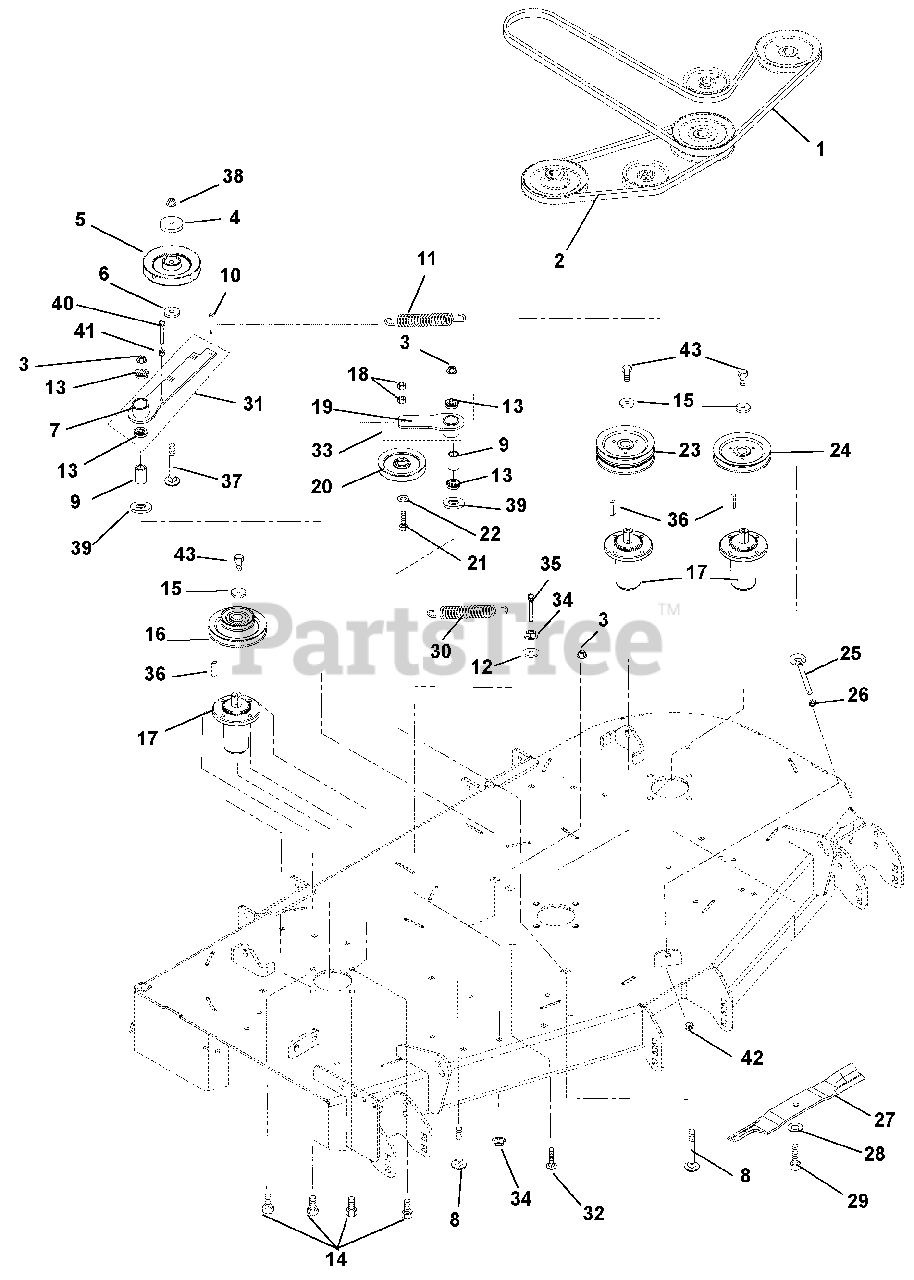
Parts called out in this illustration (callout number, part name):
1	Belt, 130" Long, PTO Drive Hex
2	V-Belt, 63" Long Cog B-Section
3	Nut, .50-13 Nyloc Flange
4	Cap, Idler Bearing Sealing
5	Sheave, .50" ID x 6.00" OD V-Idler
6	Bushing, Spacer .502 x .997 x .50
7	Weldment, Idler Arm
8	Bolt, Round Head Square Neck .50-13 x 3.25
9	Spacer .510 x .75 x 1.1485
10	Bolt, Shoulder .38-16 x .30 Hex
11	Spring, Extension
12	Washer, Flat Steel .406 x 1.375 x .135
13	Bearing, Ball, .50 x 1.38 x .438
14	Bolt, Hex .38-16 x 1.00
15	Retainer, Sheave
16	Sheave, Double, 1" ID x 6.75" x 4.25" OD
17	Spindle Assembly
18	Nut, Locking Center .38-16
19	Weldment, Idler Arm - RH
20	Assembly, V-Idler 5.00 O.D.
21	Bolt, Hex .38-16 x 2.25
22	Washer, Flat Steel .406 x .812 x .065
23	Sheave, Double 1" ID x 6.75" OD
24	Sheave, Single 1" ID x 6.75" OD
25	Bolt, .38-16 x 5.50 .62 Diameter Eye
26	Nut, Hex, Jam .375-16
27	Blade, Mower (20.50")
28	Washer, Bellville .63 x 1.625 x.14
29	Bolt, Hex .62-18 x 1.75 Grade 8
30	Spring, Extension
31	Assembly, PTO Idler Arm
32	Bolt, Round Head Square Neck .50-13 x 1.5, Full Thread, Grade 5
33	Assembly, Right Hand V-Side Idler Arm
34	Nut, Spin Lock-Flange .375-16
35	Bolt, Hex .38-16 x 3.00 Grade 5 YZ
36	Key, Square .25 x .25 x 1.00
37	Bolt, Round Head Square Neck .50-13 x 3.00 Grade 5
38	Nut, Locking Nylon-Flange .50-13
39	Spacer, Idler Arm
40	Bolt, Hex .38-16 x 2.75
41	Nut, Hex .38-16
42	Nut, Locking Nylon-Flange .38-16
43	Bolt, 3/8-16 x 2.75 Grade 8
